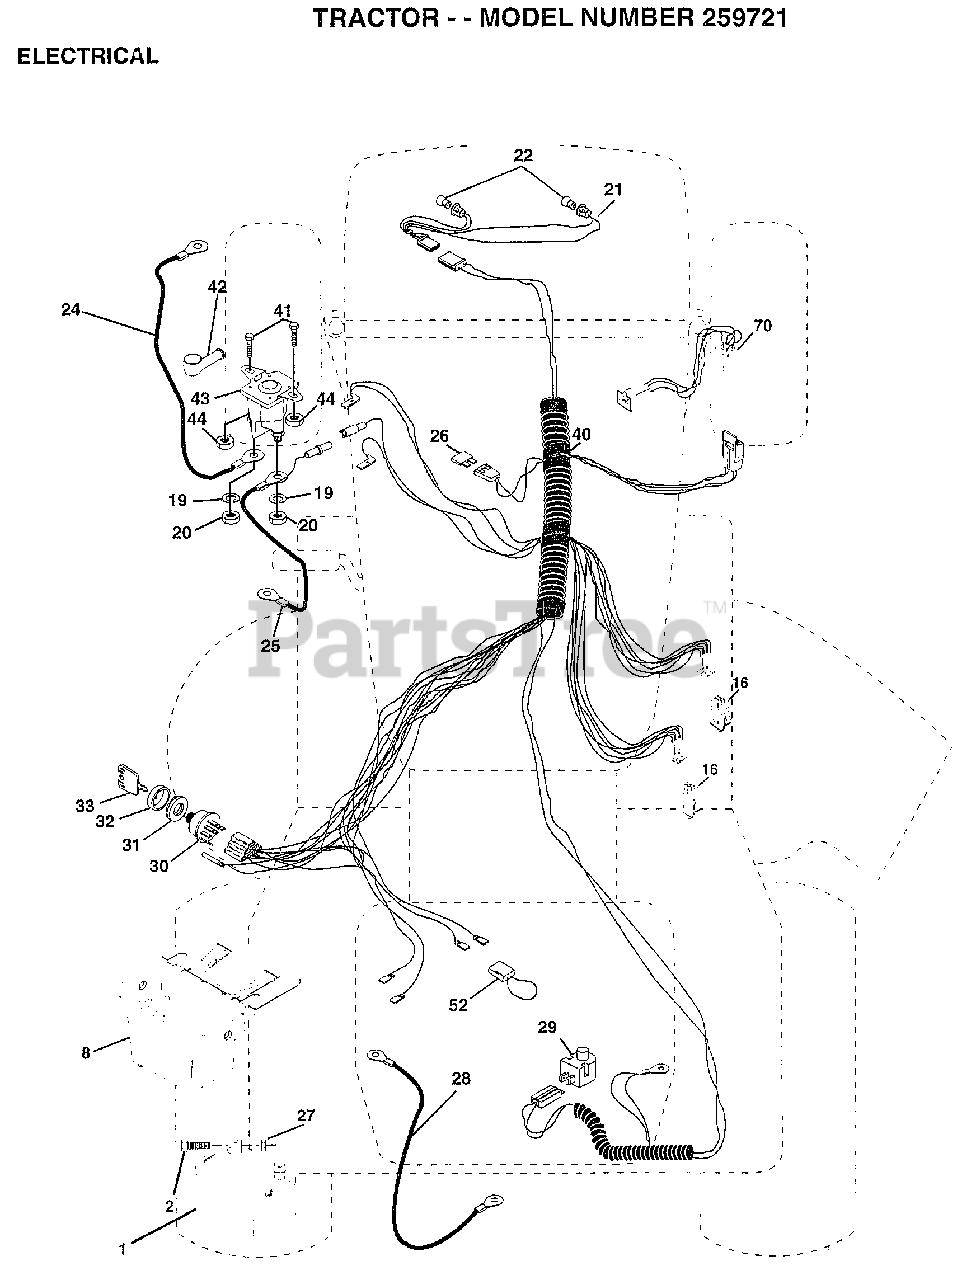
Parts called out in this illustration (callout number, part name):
2	BOLT LT
8	"CASE,BATTERY.MECH"
16	SWITCH INTERLOCK
20	NUT
21	HARNESS.ASM.LIGHT W/4152J
22	HEADLAMP BULB
24	CABLE ASM.
25	CABLE.BTRY.6GA.RD
26	FUSE.15 AMP
27	NUT
28	CABLE T
29	SWITCH SEAT
30	SWITCH IGN 4POS
31	NUT IGNITION
32	COVER KEY SWITCH
33	KEY
40	HARNESS.IGNITION
41	BOLT HXHD FIN
44	NUT HXKEP 1/4X20
48	ADAPTER AMMETER
52	PROTECTION LOOP
70	HARNESS.ENG.TEC/KOHL
